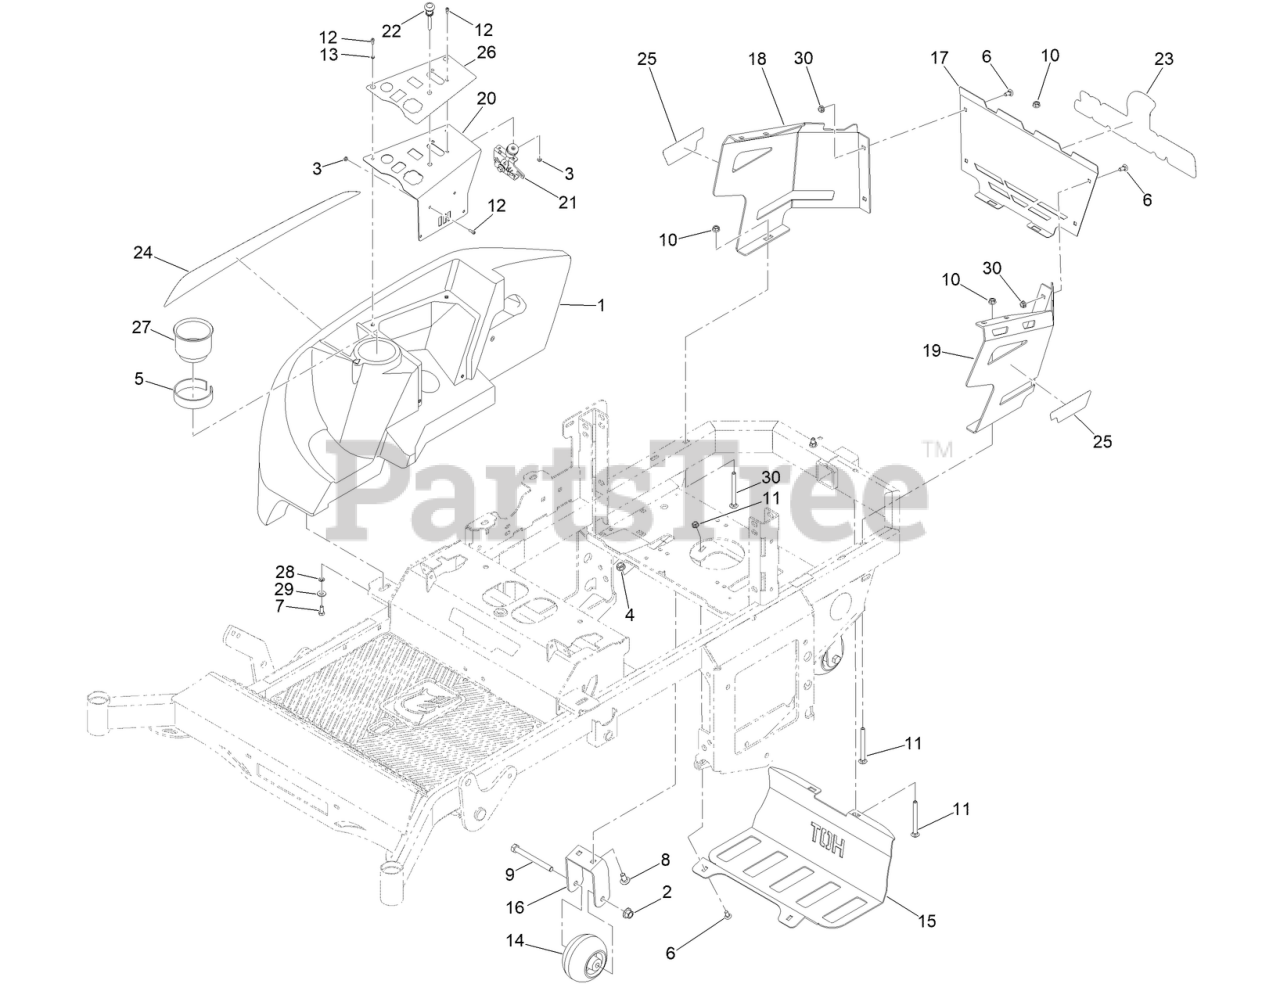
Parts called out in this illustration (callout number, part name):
1	CONSOLE W/ CUPHOLDER
2	NUT-LOCK
3	NUT-LOCK
4	NUT-HF
5	TAPE-FOAM
6	BOLT-CARR
7	SCREW-HH
8	SCREW-CARR
9	SCREW-HH
11	3/8-16 X 4 CARRIAGE BOLT ZINC
12	10-24 X 1/2 SOCKET C/S 18-8 SS
13	#10 SPLIT LOCKWASHER 18-8 SS
14	MWR ANTI-SCALP WHL W/O GREASE FITTING
15	MWR MUFFLER GUARD PAINT
16	MWR STABILIZER MTG BRKT PAINT
17	PLATE - ENGINE COWLING
18	2021 RT/SRT ENGN COWLING RTPAINTED
19	2021 RT/SRT ENGN COWLING LT PAINTED
20	CONTROL PANEL BRKT INDIV CONTROLS PAINT
21	MWR THROTTLE CABLE ASSY W / HANDLE
22	MWR CHOKE CABLE ASSM
23	MWR RR SPARTAN LOGO
24	MWR FUEL TANK LOGO RT SIDE
25	SRT XDE ENGN COWLING DECAL
26	RZ-HD/RT/SRT/KGZ-XDE KEYSWTCH CONSL DECL
27	CUP HOLDER
28	WASHER-LOCK
29	WASHER-FLAT
